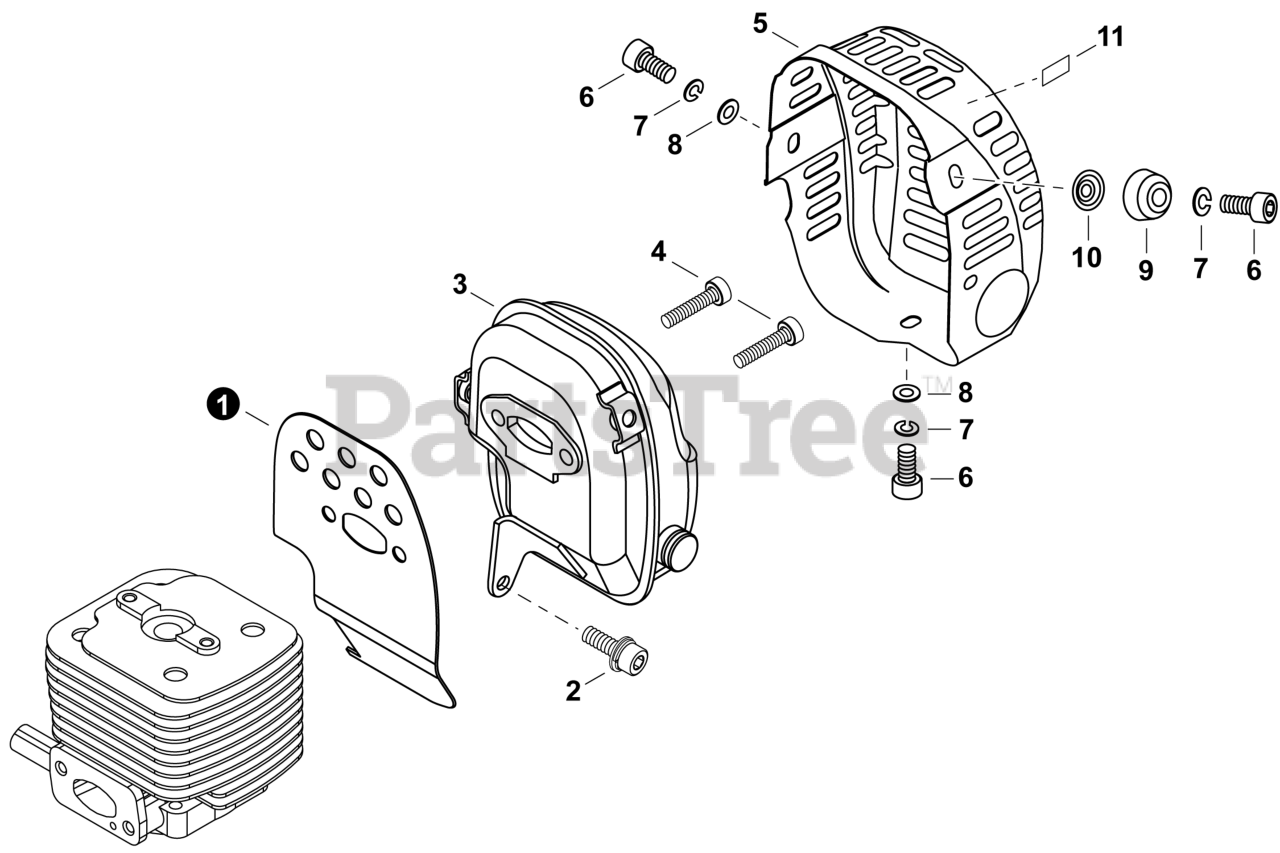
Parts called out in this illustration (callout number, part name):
1	HEAT SHIELD, EXHAUST
2	BOLT M5x12
3	MUFFLER
4	BOLT 6x25
5	COVER, MUFFLER
6	BOLT 5x10
7	WASHER, SPRING 5
8	WASHER 5.5x12x0.8
9	CUSHION
11	LABEL - CAUTION - HOT
